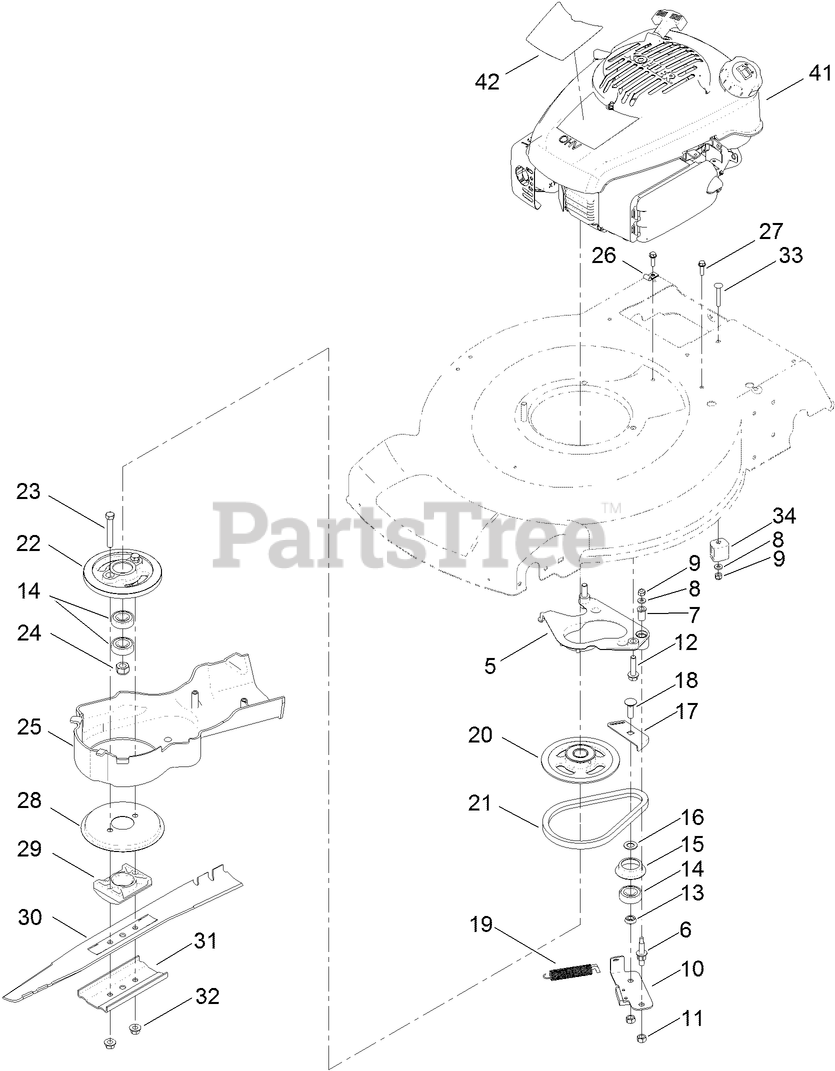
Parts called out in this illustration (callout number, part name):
5	PLATE-ANCHOR
6	BOLT-SHOULDER
7	BUSHING
8	WASHER-FLAT
9	NUT-LOCK, NI
11	LOCKNUT
12	SCREW-HWH
13	SPACER-BEARING
15	RETAINER-BELT
16	SPACER
17	PLATE-GUIDE
18	BOLT-CARR
19	SPRING-TENSION, BRAKE
20	PULLEY
21	BELT
23	SCREW-HH
24	NUT-HEX
26	CLIP-CLOSED, INSULATED
27	SCREW-HWH
28	DISC
29	SUPPORT-BLADE
31	SUPPORT-BLADE
32	NUT-LOCK
33	SCREW-CARR
34	ANCHOR-CABLE
42	DECAL-ENGINE
